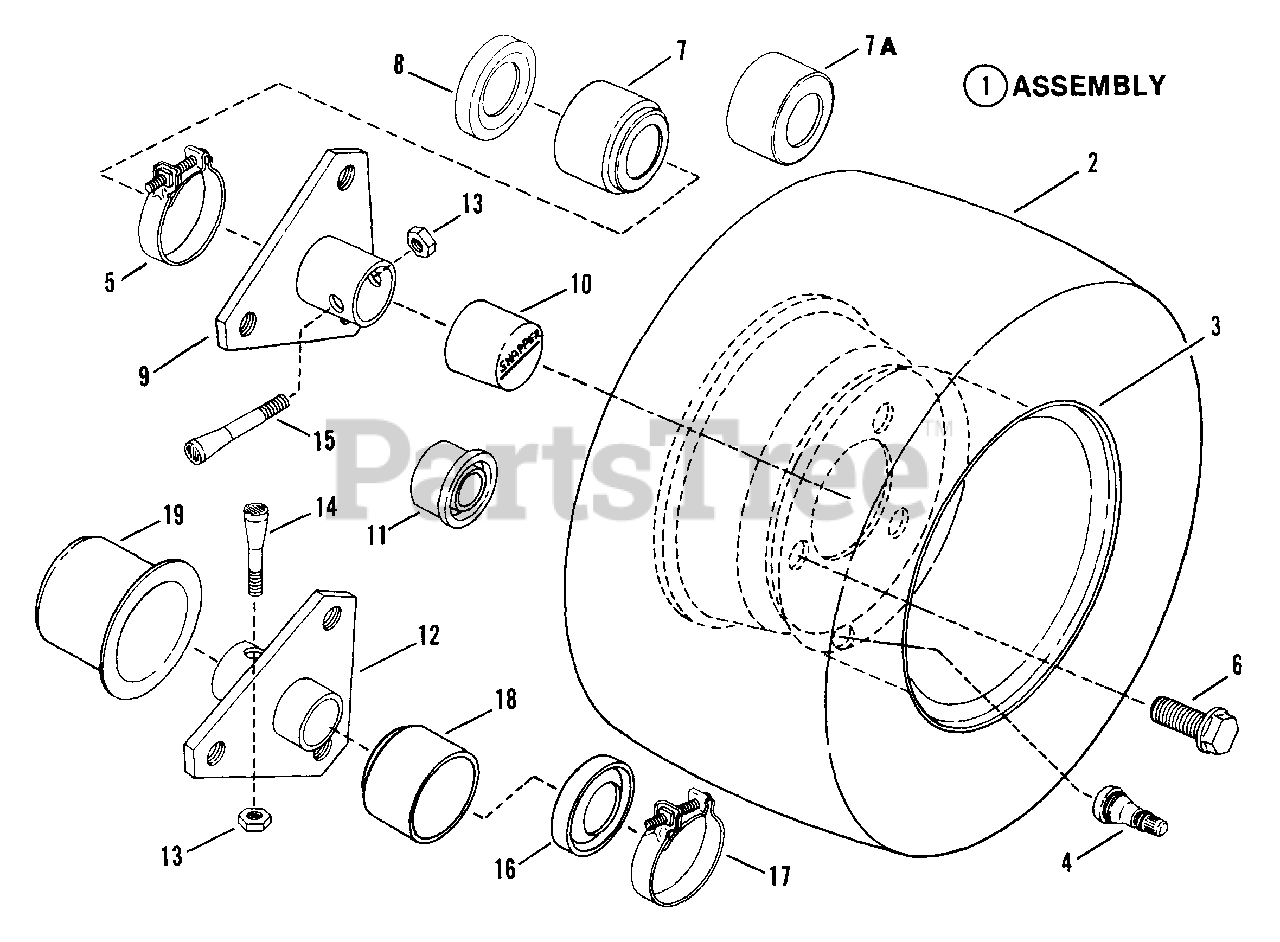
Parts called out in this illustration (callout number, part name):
1	ASSEMBLY, Rear Tire & Rim (16x4.80-8)
1	ASSEMBLY, Rear Tire & Rim (16x6.50-8)
1	ASSEMBLY, Rear Tire & Rim (16x7.50-8)
2A	TIRE, Std., 16x4.80-8
2B	TIRE, Wide, 16x6.50-8
2C	TIRE, Ext Wide, 16x7.50-8
3A	RIM, Std., (For 16x4.80-8 Tire)
3B	RIM, Wide, (For 16x6.50-8 Tire)
3C	RIM, Ext Wide, (For 16x7.50-8 Tire)
4	VALVE, Air (Snap-in)
5	CLAMP, Right Hand 1.875" (8 & 10 HP)
5	CLAMP, Right Hand 2.69" (11.5, 12.5, 14, & 16 HP)
6	BOLT, 1/2-20 x 3/4" Lug (6)
7	BOOT, Right Hand (2.625" OD, 1" Hole) (11.5, 12.5, 14 & 16 HP)
7A	BOOT, Right Hand (1.687" OD, 1" Hole) (8 & 10 HP)
8	SEAL 1.22" ID x 1.875" OD
9	HUB, Wheel RH, 3 Hole 1" ID
10	CAP, Hub
11	CAP, Seal (Left Hand) (8 & 10 HP)
12	HUB, Wheel LH, 3 Hole 3/4" ID
13	NUT, 5/1 6-24 Hex Center Lock
14	BOLT, 5/16-24 x 1-5/8" Tapered (Left Hand)
15	BOLT, 5/16-24 x 2" Tapered (Right Hand)
16	SEAL, OIL .750" ID x 1.832" OD (Left Hand)
17	CLAMP, 2" (Left Hand) (11.5, 12.5, 14 & 16HP)
18	BOOT, LH Ball Bearing Models 3/4" (11.5, 12.5, 14 & 16HP)
19	CAP, Hub (Left Hand)
